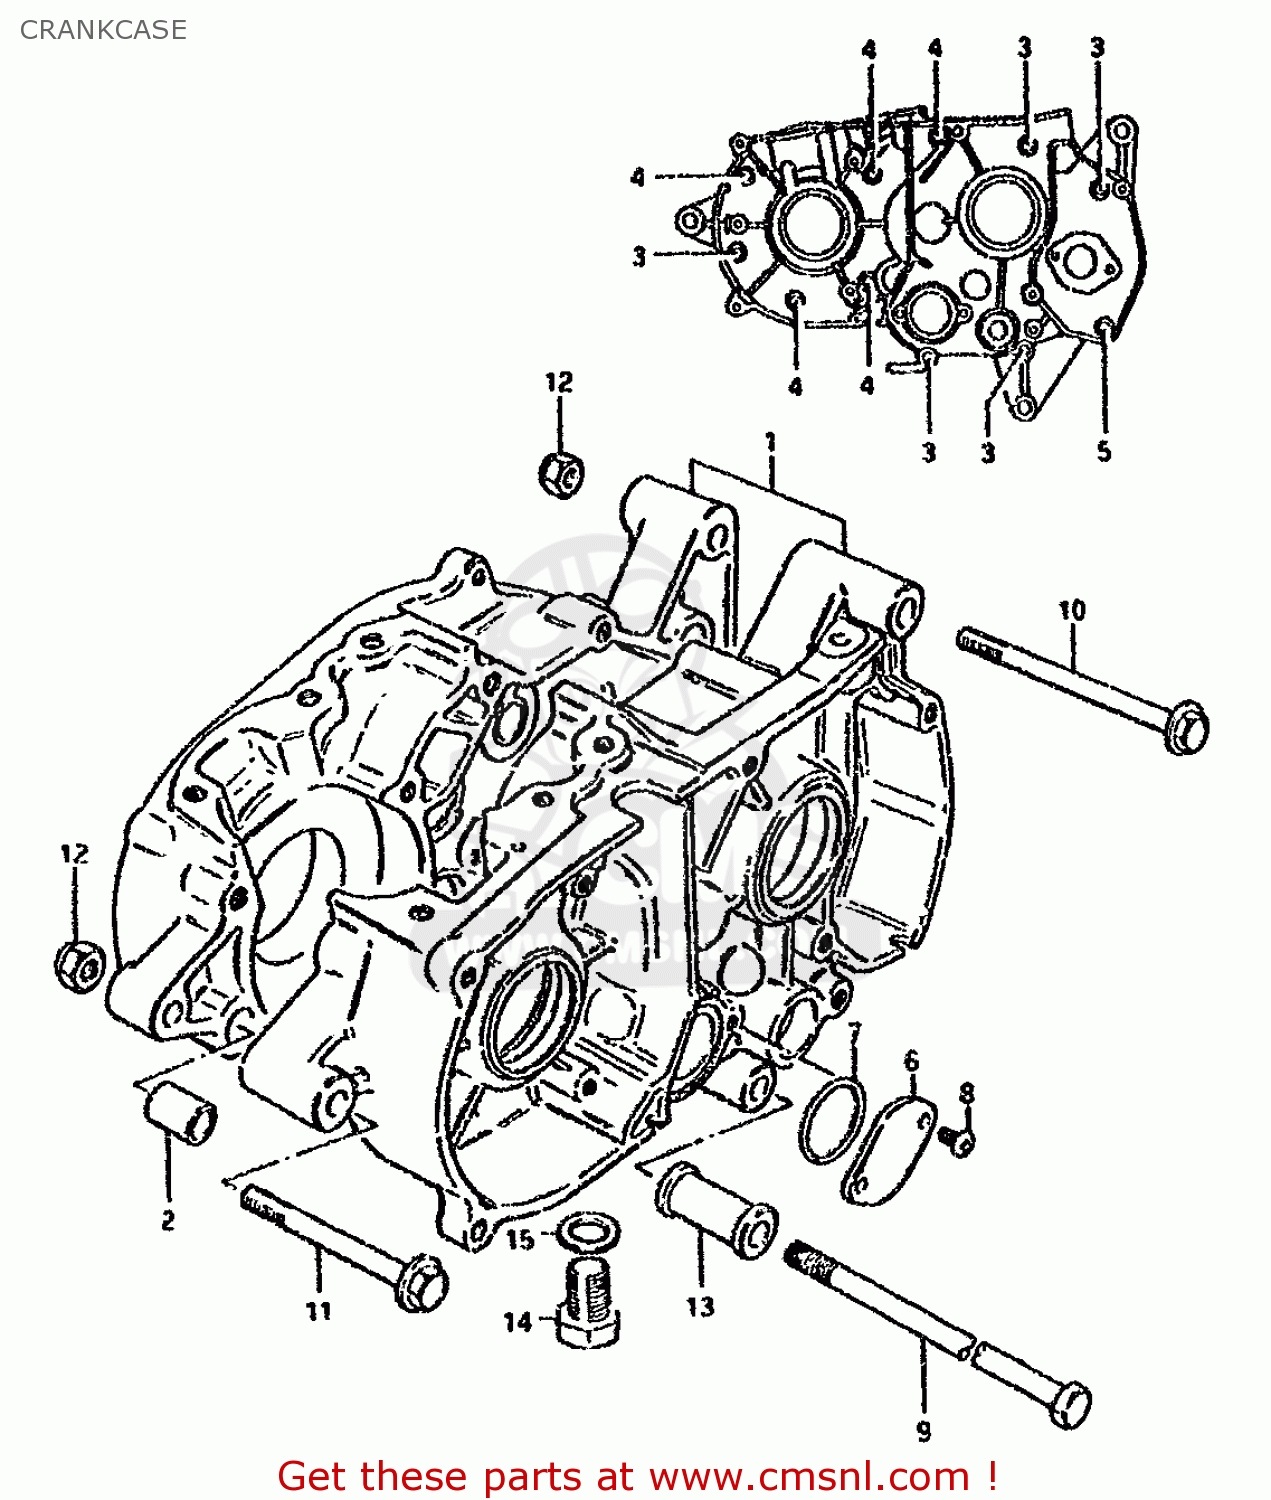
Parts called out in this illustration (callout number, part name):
1	CRANKCASE ASSEMBLY
2	PIN
3	SCREW
4	SCREW
5	SCREW
6	CAP,GEAR SHIFT CAM PIVOT
7	O-RING (D:2.4 ID:26.2)
8	SCREW
9	BOLT(8X230)
10	BOLT(8X100)
11	BOLT(8X70)
12	NUT
13	SPACER,ENGINE MOUNT(L:46)
14	BOLT
15	GASKET(10X14X3.6) (NAS)
